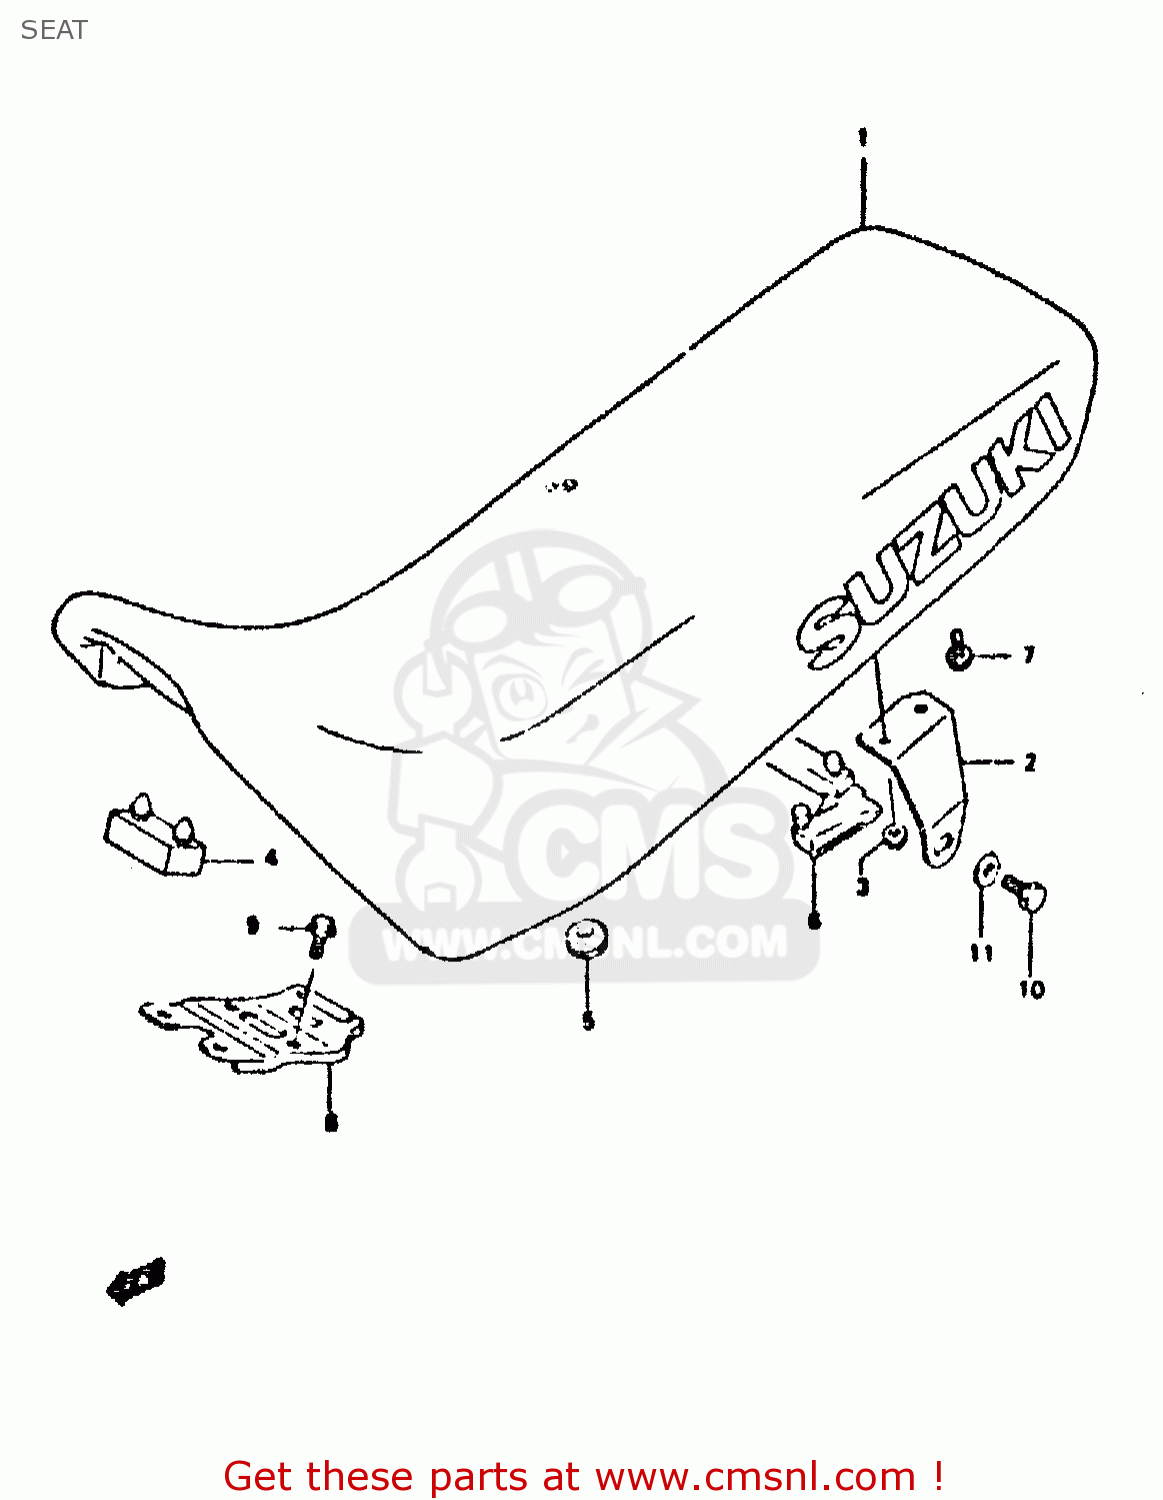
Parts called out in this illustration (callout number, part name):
1	SEAT SET
2	BRACKET,SEAT,R
3	NUT
4	CUSHION
5	CUSHION
6	CUSHION
7	BOLT
8	PLATE,SEAT FR HOOK
9	BOLT
10	BOLT
11	WASHER
